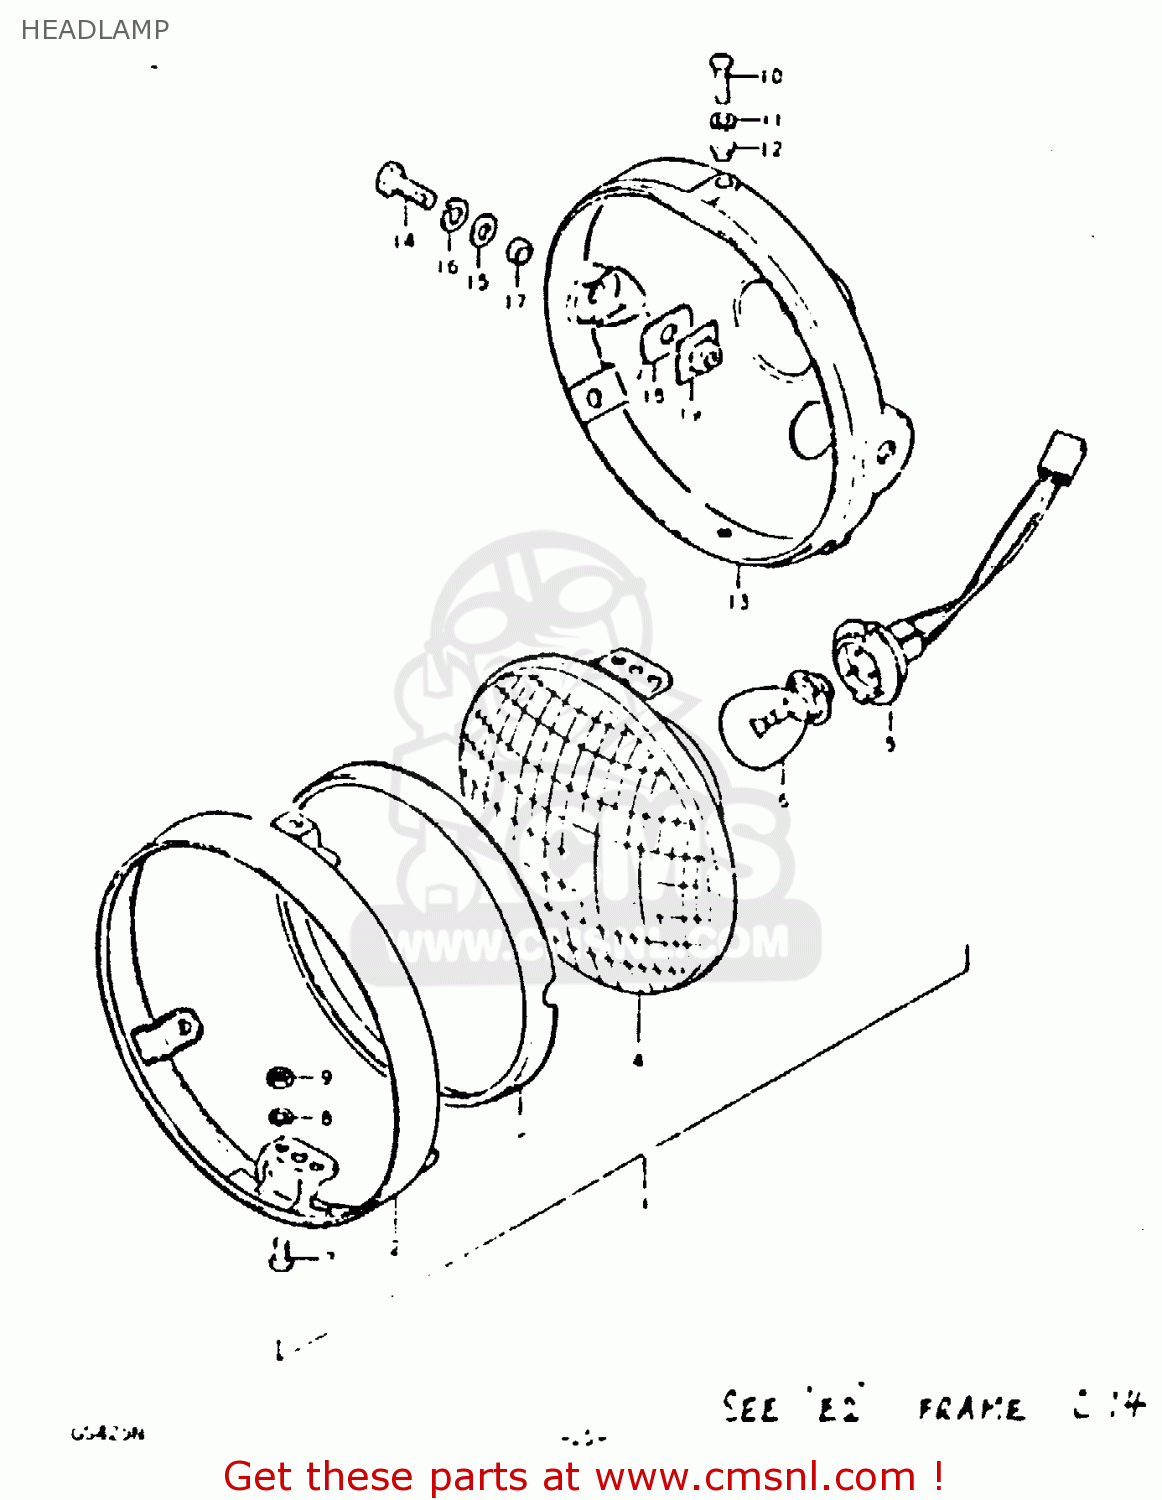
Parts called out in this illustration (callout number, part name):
1	HEADLAMP ASSY
2	RIM
3	RETAINER,HEADLAMP
4	UNIT
5	SOCKET
6	BULB
7	SCREW
8	LOCK WASHER
9	NUT
10	SCREW
11	WASHER,LOCK
12	WASHER
13	HOUSING,HEADLAMP(BLACK)
14	BOLT
15	WASHER
16	LOCK WASHER
17	SPACER (8.8X12X7)
18	CUSHION
19	PLATE,HEADLAMP HOUSING
